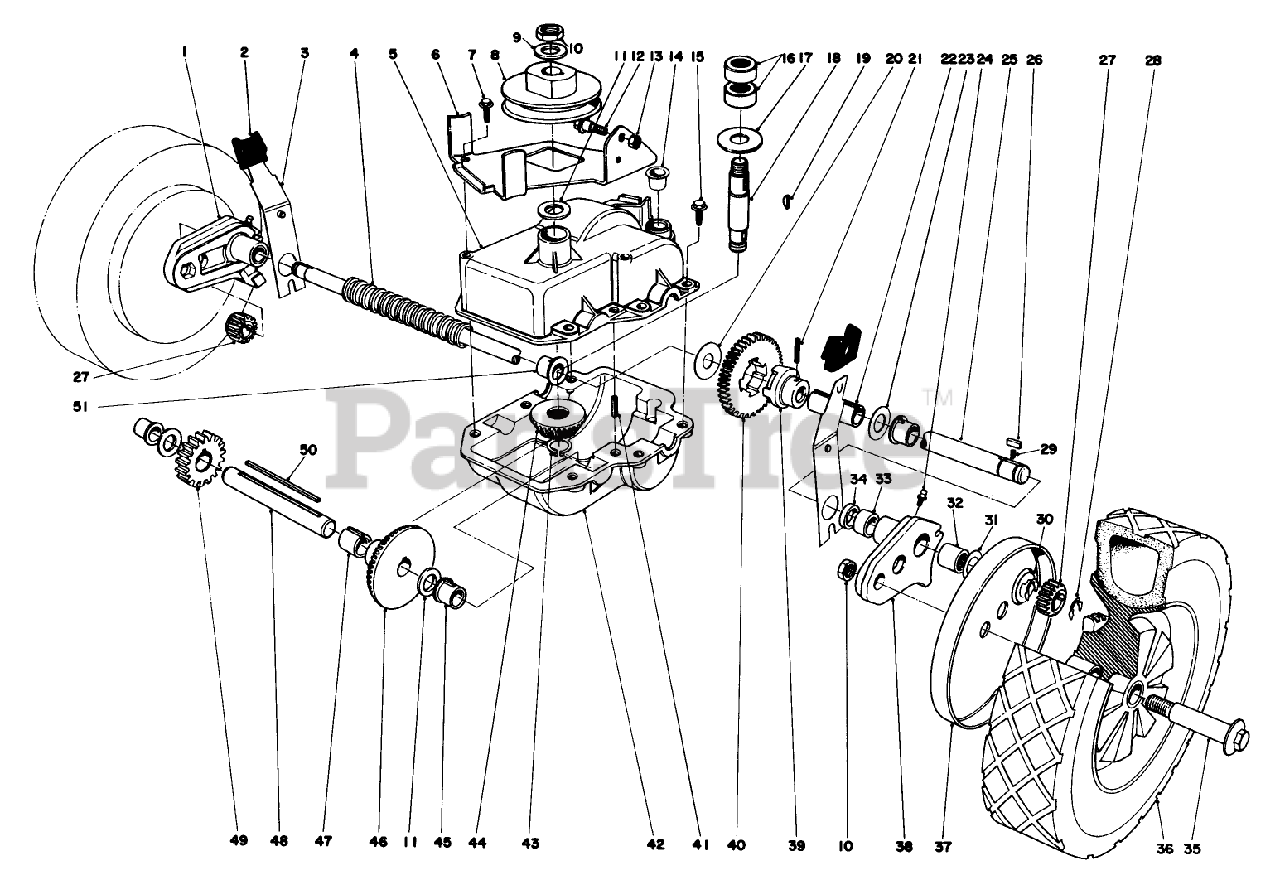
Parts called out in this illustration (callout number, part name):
1	Pivot Arm R.H. (Incl. Ref. #24 & 32-34)
2	KNOB-ARM
3	Spring Arm
4	Cover Drive Shaft
5	Case Upper
6	Bracket-Belt Guide
7	Screw
8	PULLEY
9	WASHER-FLAT
10	Nut
11	WASHER-THRUST
12	BOLT-SHOULDER
13	NUT-LOCK, NI
14	Caplug
15	SCREW-HWH, THREAD ROLL
16	Bearing
17	Thrust Washer
18	INPUT SHAFT
19	KEY-WOODRUFF
20	WASHER
21	COIL PIN
22	Spacer-Output Shaft
23	WASHER-PLAIN
24	FITTING-GREASE
25	Output Shaft
26	KEY RECTANGULAR
27	GEAR-PINION
28	RING-RETAINING
29	SPRING-COMPRESSION
30	THRUST WASHER
31	Washer
32	Needle Baring
33	Bushing
34	Seal
35	BOLT-WHEEL
36	Wheel & Tire Assembly
37	Cover-Wheel
38	Pivot Arm L.H. (Incl. Ref. #24 & 32-34)
39	ADAPTER DRIVE
40	Gear
41	ROLL PIN 3/16 X 1 IN
42	LOWER GEAR CASE CAST
43	RING-RETAINING
44	PINION-BEVEL
45	Botching Shaft
46	BEVEL GEAR
47	Shaft-Pivot
48	Sort Shaft
49	14 T GEAR
50	Key Square
51	Bushing
